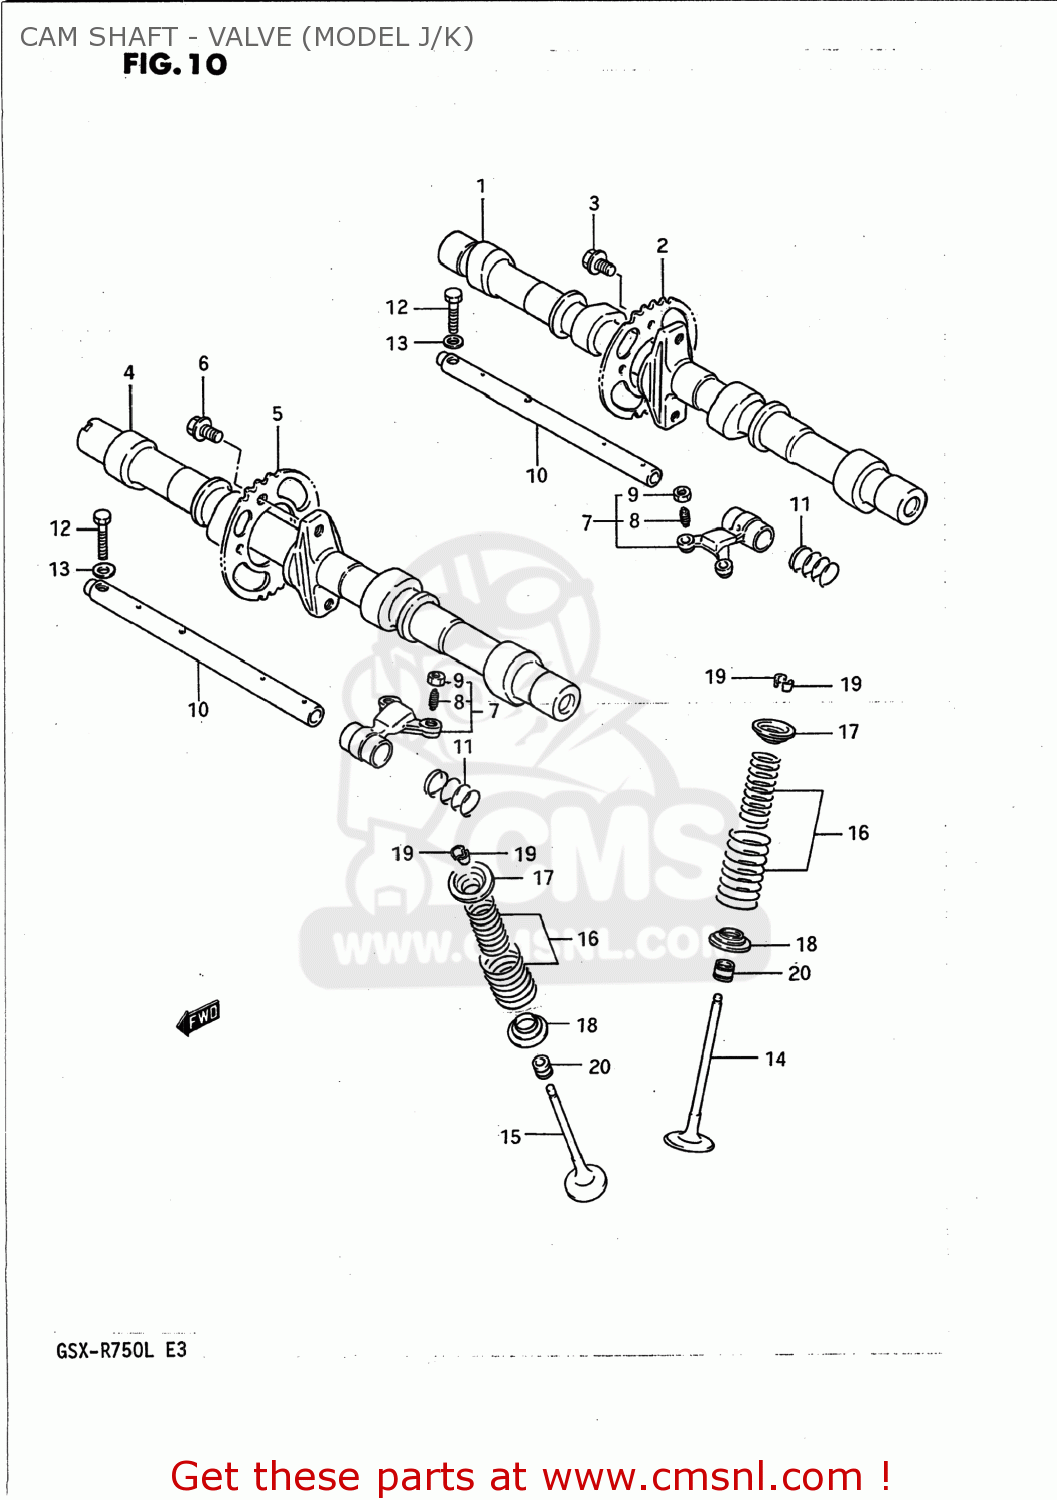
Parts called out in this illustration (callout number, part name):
1	CAMSHAFT
2	SPROCKET,CAMSHAFT
3	BOLT(7X11)
4	CAMSHAFT,EXHAUST
5	SPROCKET,CAMSHAFT
6	BOLT(7X11)
7	ARM,VALVE ROCKER
8	SCREW,TAPPET ADJUSTING
9	NUT,ADJUSTING
10	SHAFT,VALVE ROCKER ARM
11	SPRING
12	BOLT
13	WASHER, LOWER
14	VALVE,INTAKE
15	VALVE,EXHAUST
16	SPRING SET,VALVE
17	RETAINER,VALVE SPRING
18	SEAT,VALVE SPRING
19	COTTER VALVE
20	SEAL,OIL(5X10X9.7)
